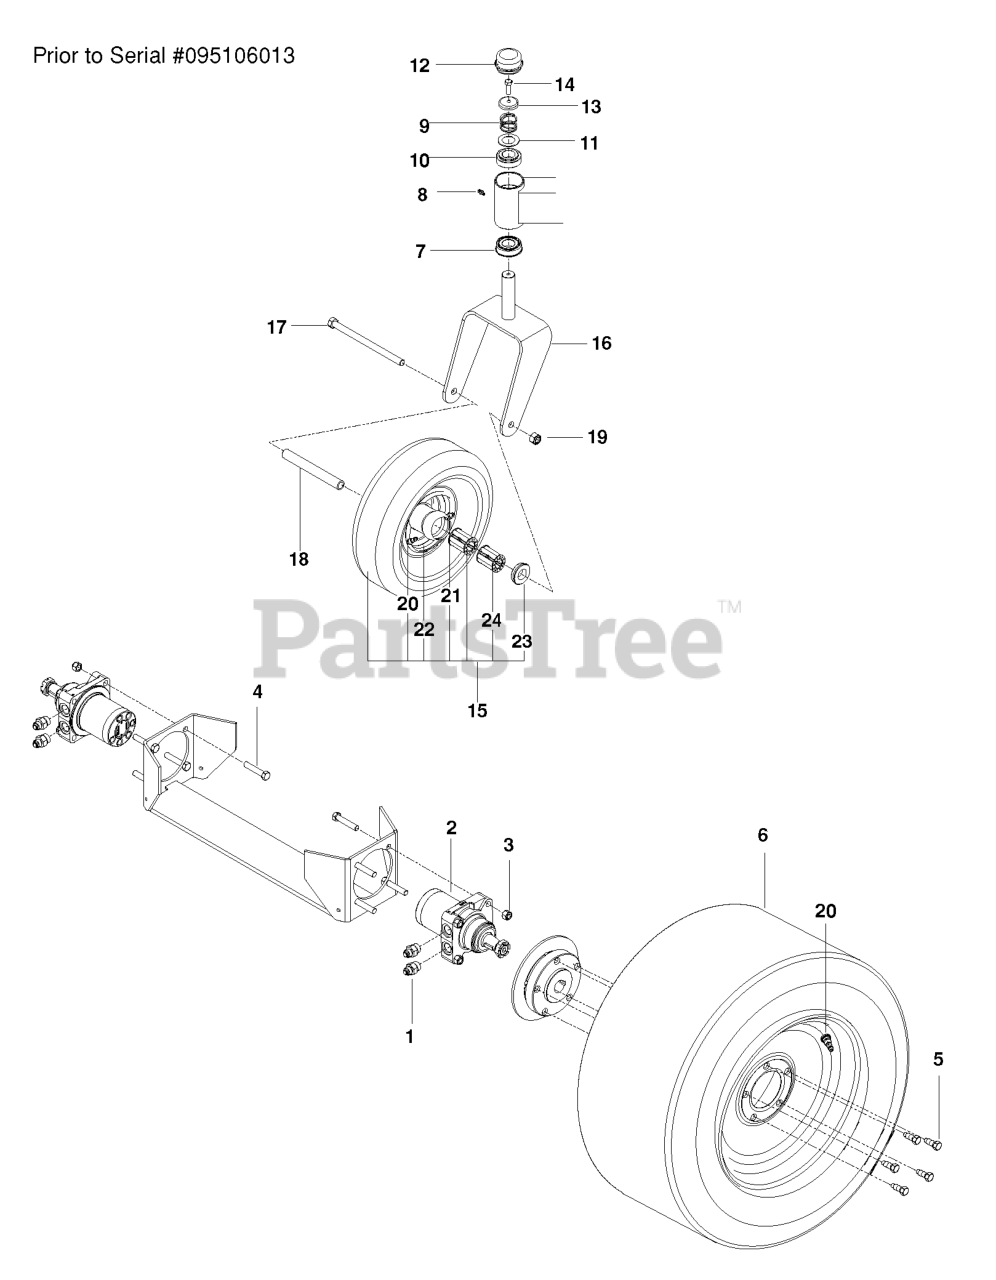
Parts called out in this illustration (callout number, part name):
1	CONNECTOR, STRAIGHT
2	WHEEL MOTOR, TJ
3	NUT 1/2-13 HEX NYLOC ZD
4	HCS 1/2C X 2 3/4
6	TIRE - CASTER
7	BEARING FLANGED
8	ZERK, 3/16, DRIVE IN
9	SPRING, CASTER
10	BUSHING, CASTER
11	WASHER, 1.025 ID X 1.64
12	GREASE CAP
13	CASTER.PLUG
14	HCS 5/16C X 1
15	TIRE.ASSEM.13X5-6.SMOOTH.SILVE
16	YOKE, CASTER
17	RHSNB 1/2-13 X 6.50 GR2 ZD
18	SPACER, CASTER
19	NUT 1/2-13 HEX NYLOC ZD
20	VALVE STEM TR-412
21	ZERK 1/8 NPT
22	RIM
23	BEARING RETAINER
24	ROLLER BEARING
